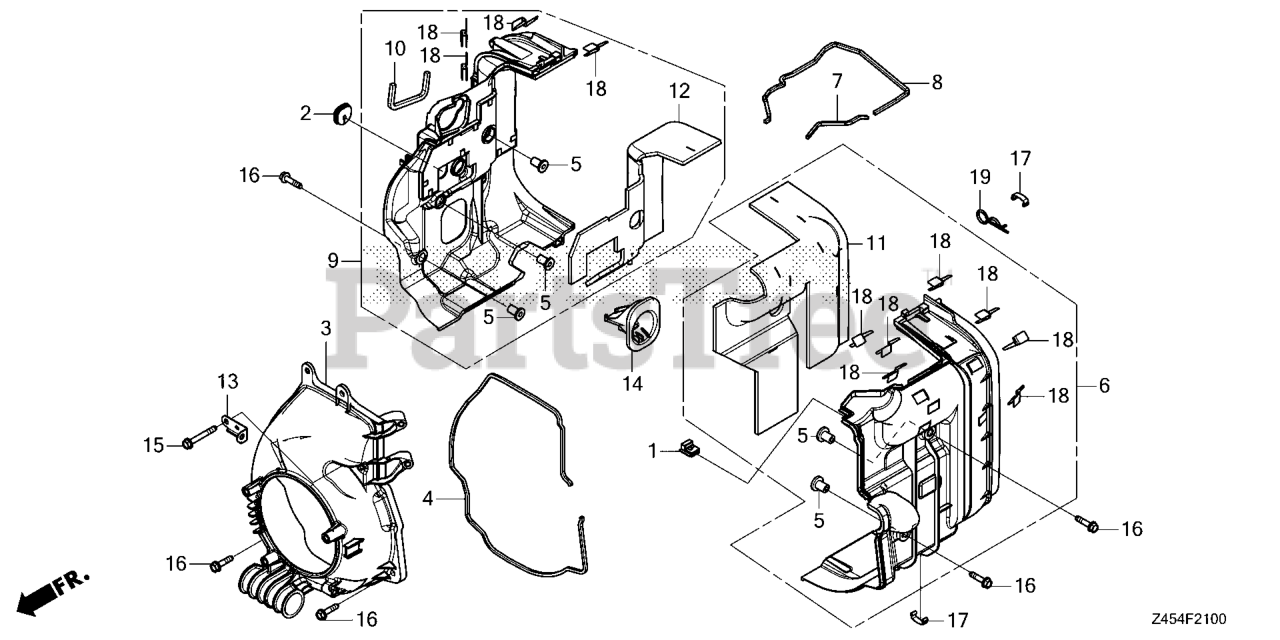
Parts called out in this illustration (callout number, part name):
1	GROM, OXYGEN SENSOR
2	GROMMET, TE SENSOR
3	COVER, FAN (0000)
4	SEAL, FAN COVER
5	COLLAR, FAN COVER
6	SHROUD ASSY., R
7	SEAL A, SHROUD
8	SEAL B, SHROUD
9	SHROUD ASSY., L
10	SEAL, L SHROUD
11	INSULATOR, R SHROUD
12	INSULATOR, L SHROUD
13	BRACKET, HARN CLIP
14	RUBBER, OIL CHECK
15	BOLT, FLANGE (6X45)
16	BOLT, FLANGE (6X25) Use up to Engine SN 2056819.
17	CLAMP, CASE
18	CLIP, INSULATOR BIND
19	PIN, LOCK (16MM)
